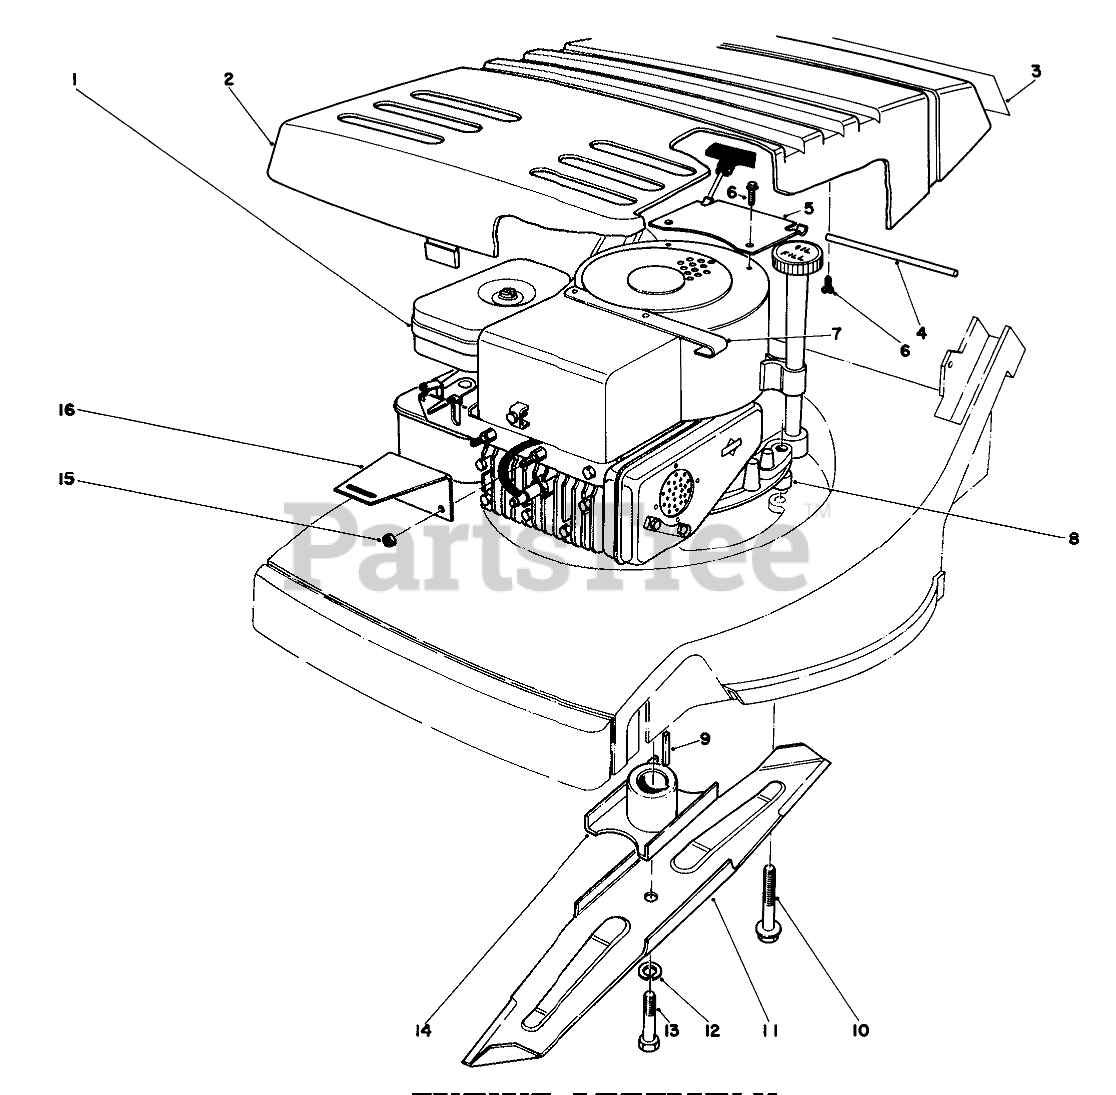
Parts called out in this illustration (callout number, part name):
1	Engine (Model No. 20815)
2	Shroud
3	Decal-Warning (Model No. 20815)
3	Decal-Warning (German) (Model No. 20830)
4	Pin-Hinge
5	Bracket-Shroud Hinge
6	8X1/2 SELF TAP SCREW
7	Cable Strap
8	SPACER
9	KEY-SQUARE
10	3/8-16 X 2 CAPSCREW
11	42 CM BLADE
12	WASHER-LOCK
13	BLADE SCREW
14	BLADE RETAINER WA(BLACK)
15	NUT-LOCK, NI
16	Bracket-Shroud
